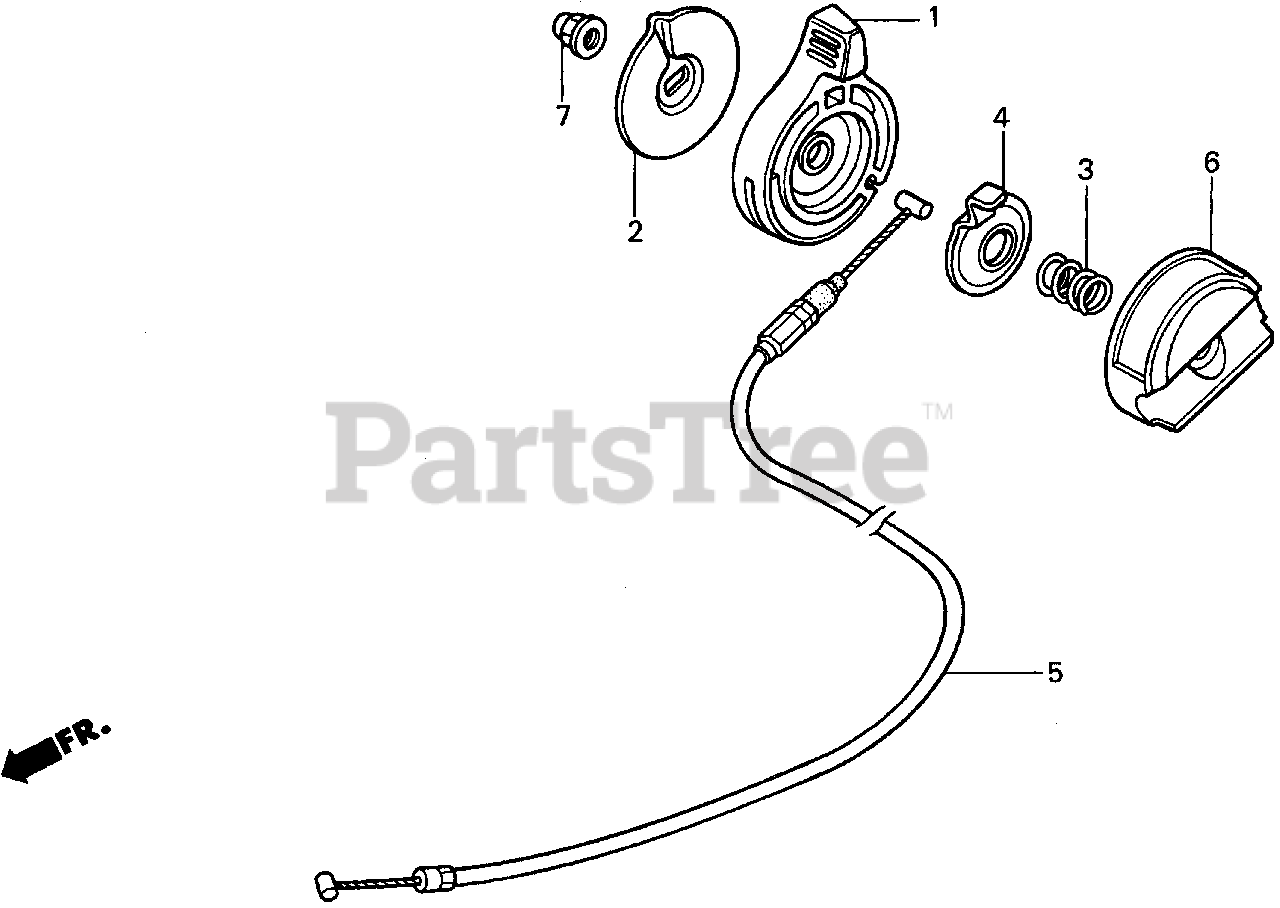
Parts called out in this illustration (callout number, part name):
1	LEVER, THROTTLE
2	PLATE, THROTTLE LEVER
3	SPRING, THROTTLE LEVER
4	SEAT, SPRING
5	CABLE, THROTTLE
6	COVER, CONTROL
7	NUT, CAP (6MM)
7	NUT, FLANGE (6MM)
